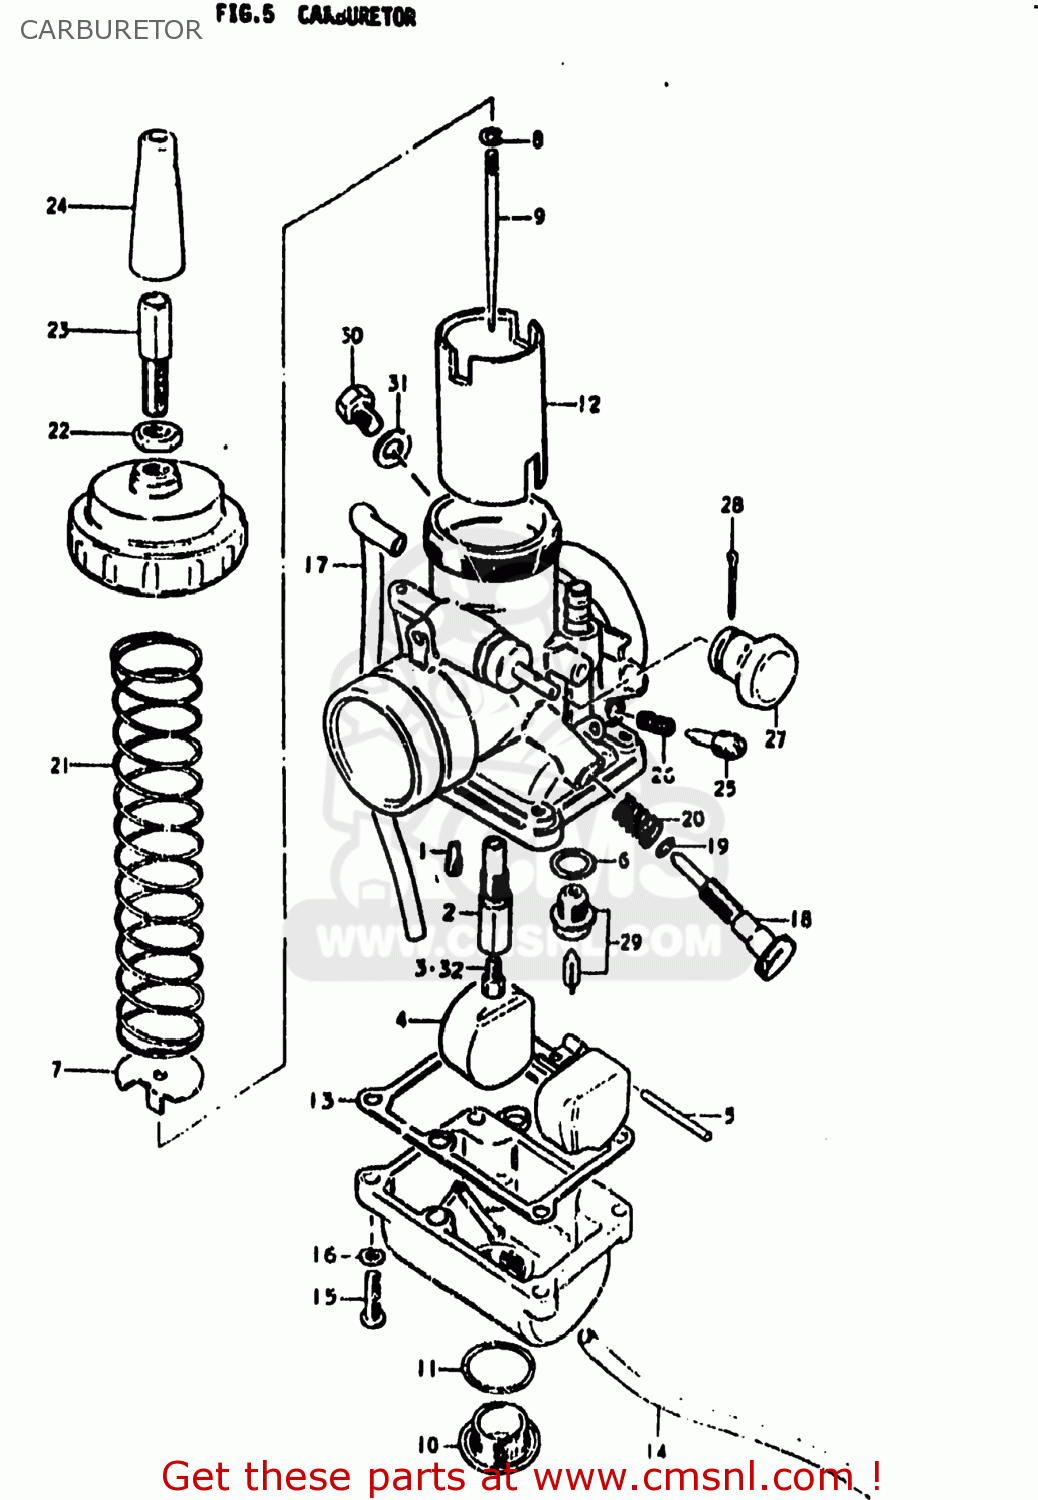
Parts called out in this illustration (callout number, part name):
1	JET,PILOT
2	JET,NEEDLE
3	JET,MAIN
4	FLOAT
5	PIN,FLOAT
6	GASKET,NEEDLE VALVE (NAS)
7	STOPPER,NEEDLE CLIP
8	CLIP
9	NEEDLE,JET
10	SCREW,GUIDE
11	O-RING
12	VALVE,THROTTLE
13	GASKET,FLOAT CHAMBER (NAS)
14	HOSE
15	SCREW
16	LOCK WASHER
17	HOSE
18	ADJUSTER
19	O-RING
20	SPRING
21	SPRING,THROTTLE VALVE
22	NUT
23	ADJUSTER,CABLE
24	CAP,CABLE ADJUSTER
25	SCREW,PILOT AIR
26	SPRING
27	LEVER
28	COTTER PIN
29	VALVE ASSY,NEEDLE
30	BOLT
31	GASKET,THRO VALVE INSPECTION (NAS)
32	JET,MAIN
